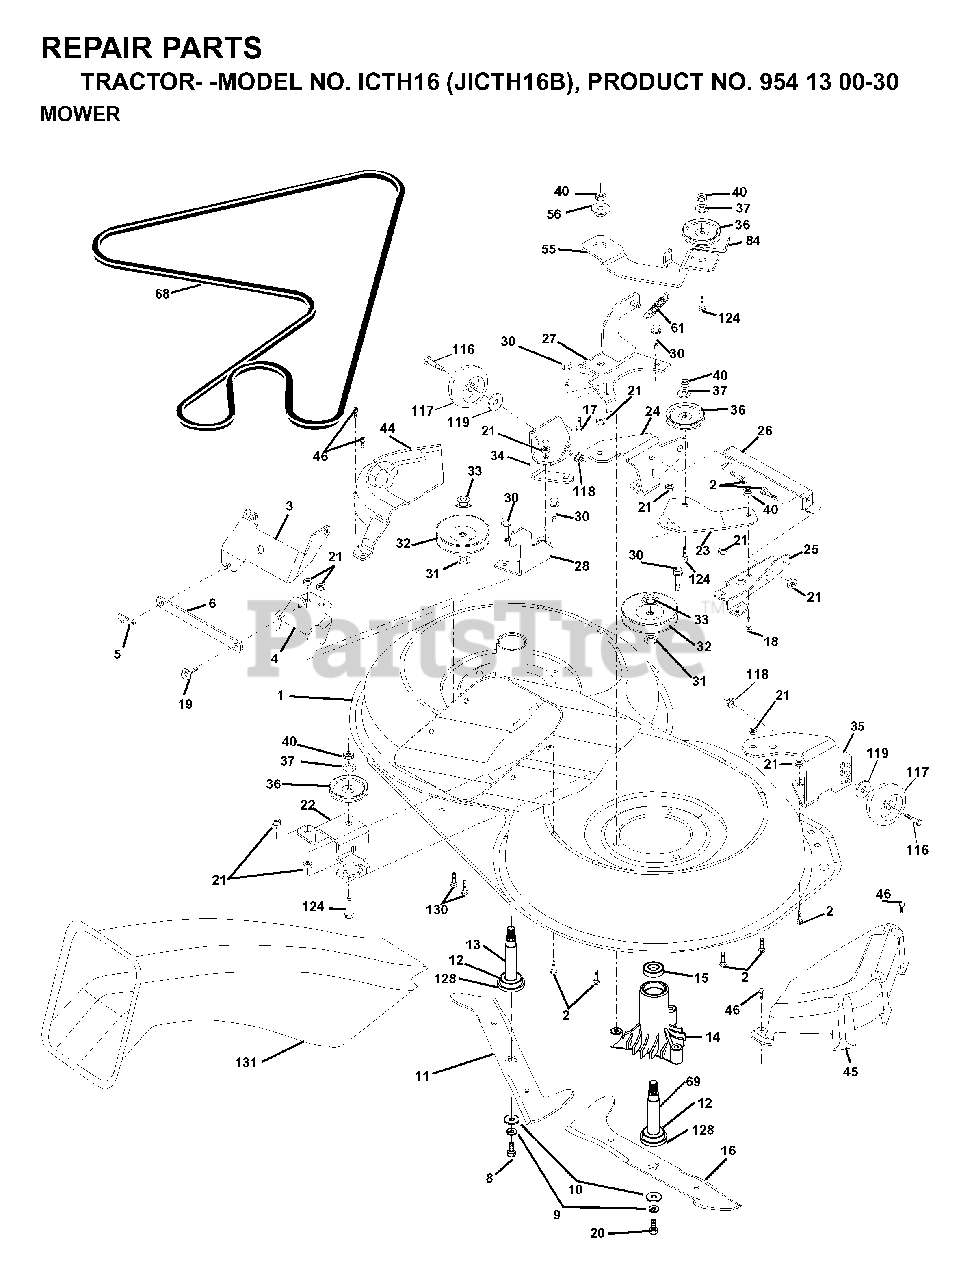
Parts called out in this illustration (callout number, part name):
1	MOWER HOUSING, DECK
2	BOLT
3	BRACKET
5	RETAINER-SPRNG RB
6	BAR SWAY
8	BLADE BOLT
9	LOCKWASHER
10	WASHER.BLADE
11	BLADE
12	BEARING
13	SHAFT ASM VENT
14	HSG MANDREL
16	BLADE
17	BOLT.3/8-14X1.25
19	BOLT SHD 5/16-18
21	LOCKNUT
24	BRACKET
25	BRACKET
26	BRACE
28	BRACKET
30	SCREW THDROL ROLLING WASHER HD
31	WASHER
32	PULLEY, MANDREL
33	NUT
36	PULLEY.IDLER.4.25
40	LOCKNUT
45	COVER
46	SCREW.1/4-20X5/8
55	ARM IDLER
56	SPACER RETAINER
61	SPRING.TENSION.BELT
68	HEX-BELT 92 MOWER 105AA
69	SHAFT.ASM.W/LWR.BRG.RH.THREAD
84	KEEPER, BELT IDLER
116	BOLT, SHOULDER
117	WHEEL GAGE DONUT
118	LOCKNUT
119	WASHER
124	BOLT.3/8-16X1.50
128	WASHER FELT
131	CHUTE BAGGER
